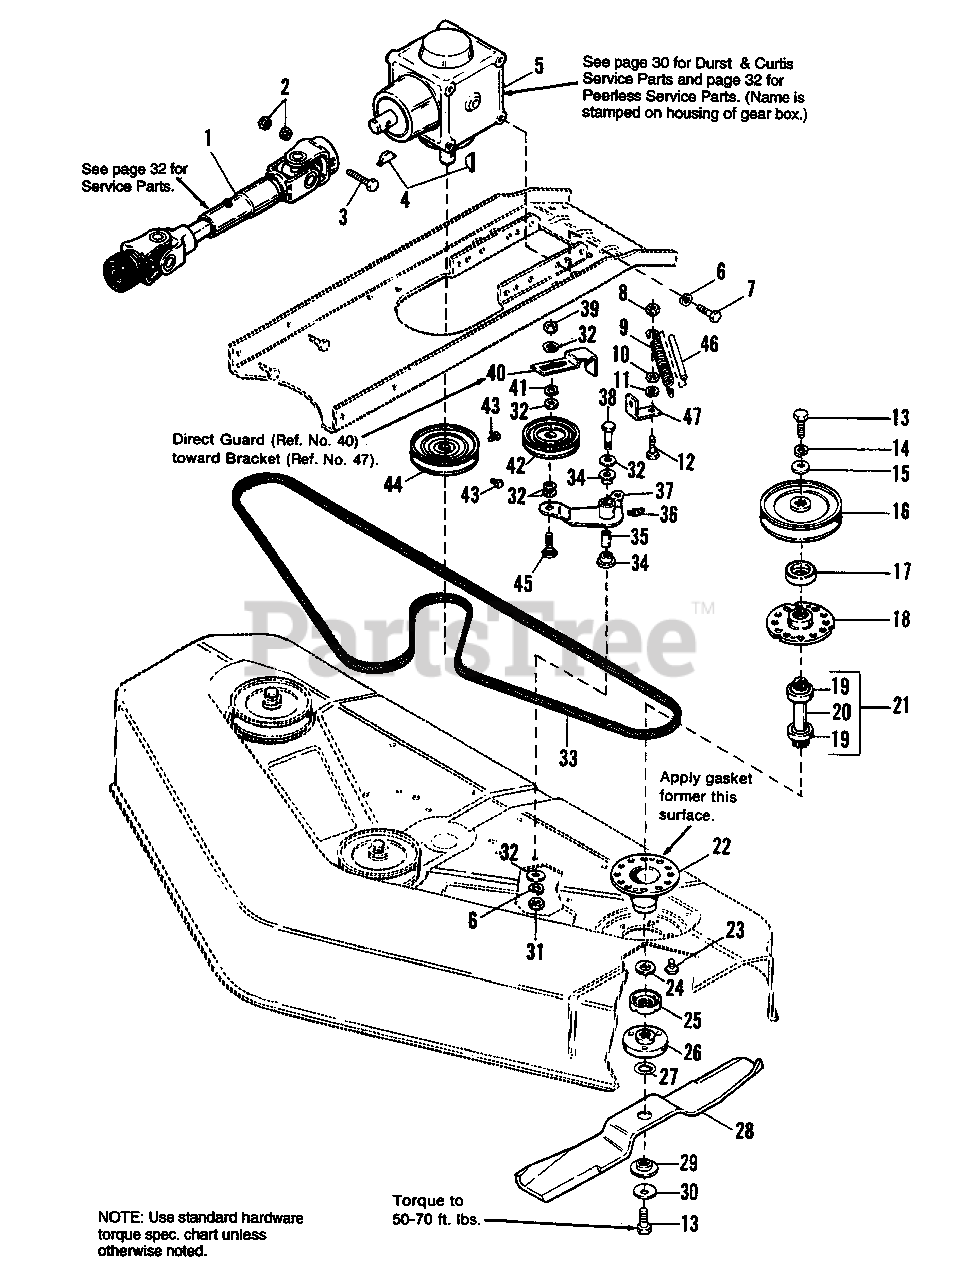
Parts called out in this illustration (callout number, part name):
1	DRIVE SHAFT ASSY., Telescoping
2	LOCKNUT, Hex, 1/4-20
3	CAPSCREW, Hex, 1/4-20 x 3
4	KEY, Hi-Pro
5	RIGHT ANGLE GEAR CASE ASSY.
6	LOCKWASHER, 5/8
7	CAPSCREW, Hex, 3/8-16 x 3/4
8	LOCKNUT, Hex, 5/16-18
10	Nut, Hex, 5/16-18
11	LOCKWASHER, 5/16
12	CAPSCREW, Hex, 5/16-18 x 1
13	CAPSCREW, Hex, 7/16-14 x 1
14	LOCKWASHER, 7/16
15	WASHER, 7/16
16	PULLEY ASSY., Arbor Drive
17	SHIELD, Bearing Upper, Arbor
18	ARBOR HOUSING, Top
19	BEARING (Arbor Shaft)
20	Shaft, Arbor
21	ARBOR SHAFT & BEARING ASSY.
22	ARBOR HOUSING, Bottom
23	SCREW, Hex, Taptite, 5/16-18 x 3/4
24	WASHER, Shim
25	SHIELD, Grass
26	ADAPTOR, Blade
27	RING, Self Locking
28	BLADE, 60" Mower
29	WASHER, Spline
30	WASHER, Spring
31	NUT, Hex, 3/8
32	WASHER, 5/16
33	BELT, Arbor Drive
36	FITTING Lube
37	LEVER ASSY., Idler
38	CAPSCREW, Hex, 3/8-16 x 2
39	LOCKNUT, Hex, Jam, 3/8-16
41	LOCKWASHER, Internal 3/8
42	PULLEY, Idler
43	SETSCREW, Sq. Hd., 5/16-1/2
44	PULLEY ASSY., Drive
45	CAPSCREW, Hex, 3/8-16 x 1-1/4
47	BRACKET
